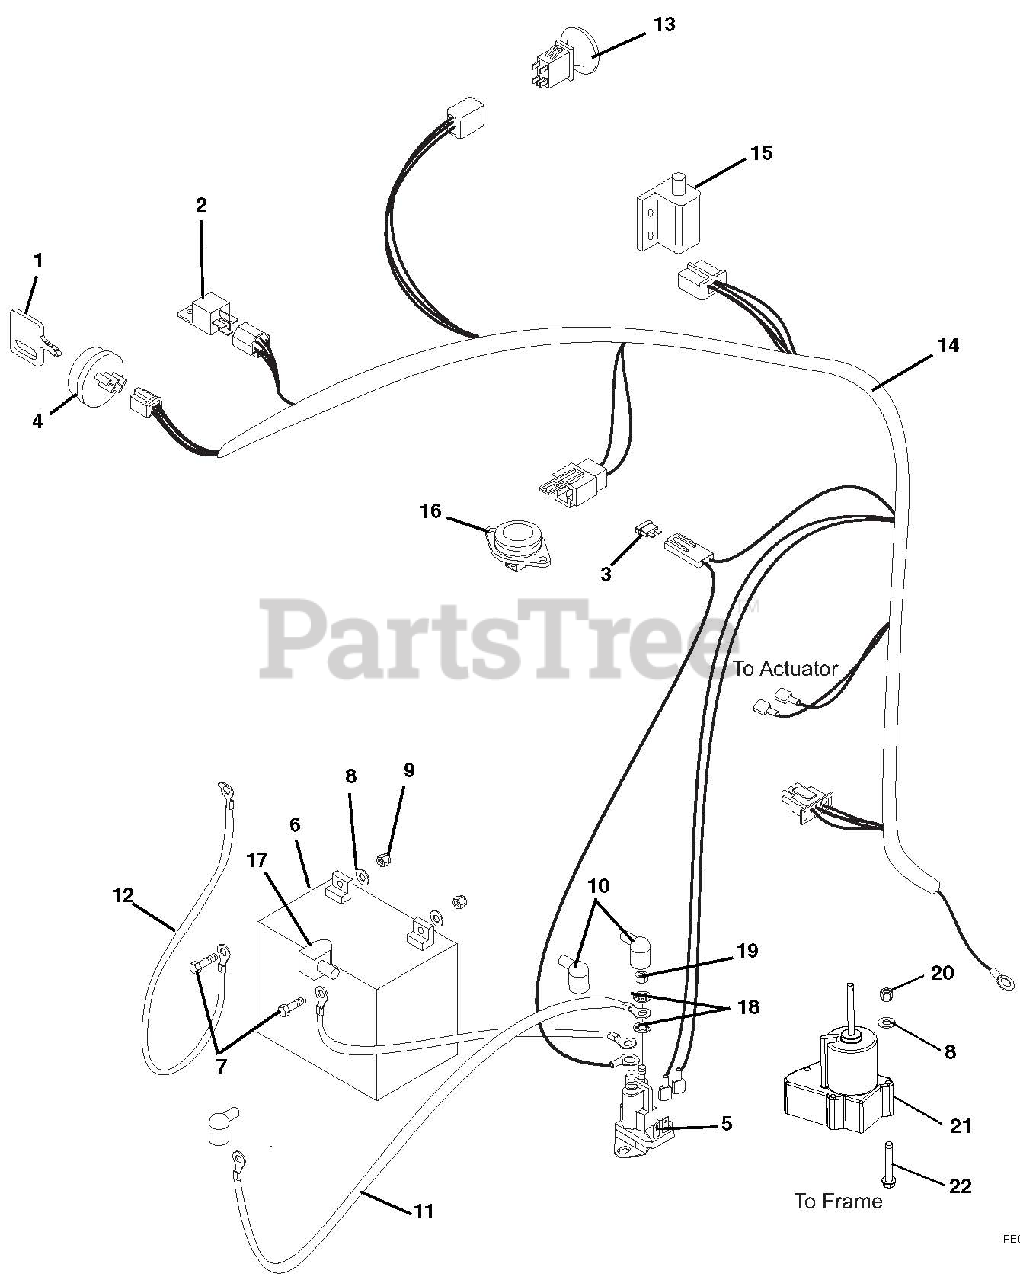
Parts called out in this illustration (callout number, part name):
1	KEY -W/CAP
2	RELAY
3	FUSE-25 AMP ATC TYPE
4	KEYSWITCH-IGNITION 3 POS
5	SOLENOID, HP RTV
7	@BLT-HEX .25-20X.75 GR5 YWZC
8	@WSHR-FL-STL.281X.62X.065 YWZC
9	NUT-KEPS .250-20
10	BOOT, EYELET TERMINAL
11	CABLE, POS. BAT. 14.25"
12	CABLE, GROUND 26.00"
13	SWITCH, CLUTCH
14	HARNESS-WIRING, BBZ
15	SWITCH- DOUBLE POLE N.O./N.O.
16	SWITCH- SNAP MTG N.O.
17	INSULATOR
18	WSHR-LOCK INT .31 YWZC
19	NUT-JAM .31-24 YWZC
20	@NUT-LK-NYL-FLG .25-20 YWZC
21	ACTUATOR-NORAM PAC 2"
22	@BLT-HEX .25-20X2.50 GR5 YWZC
